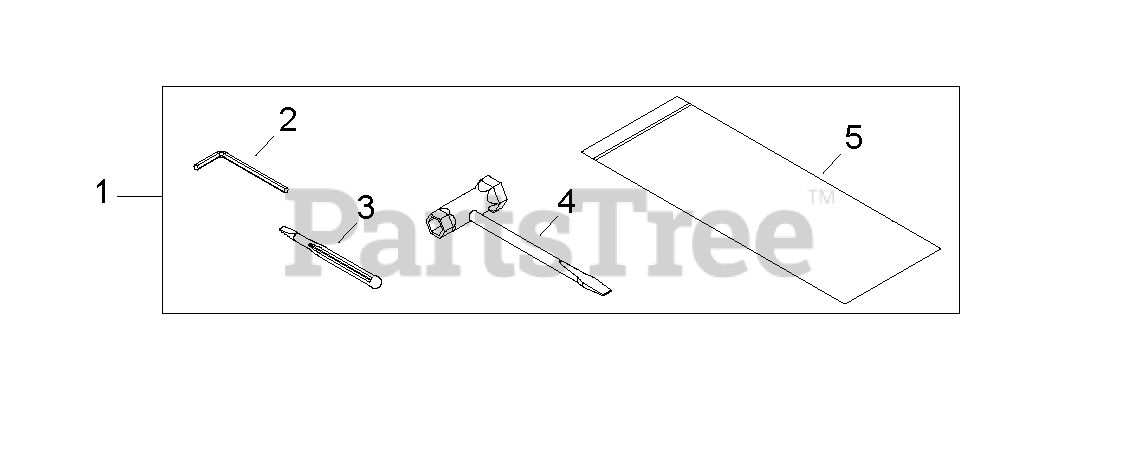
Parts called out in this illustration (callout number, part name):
1	TOOL KIT, SERVICE
2	WRENCH, ALLEN 4 MM
3	SCREWDRIVER, PLASTIC
4	T-WRENCH 13×19 MM
5	BAG, TOOL
